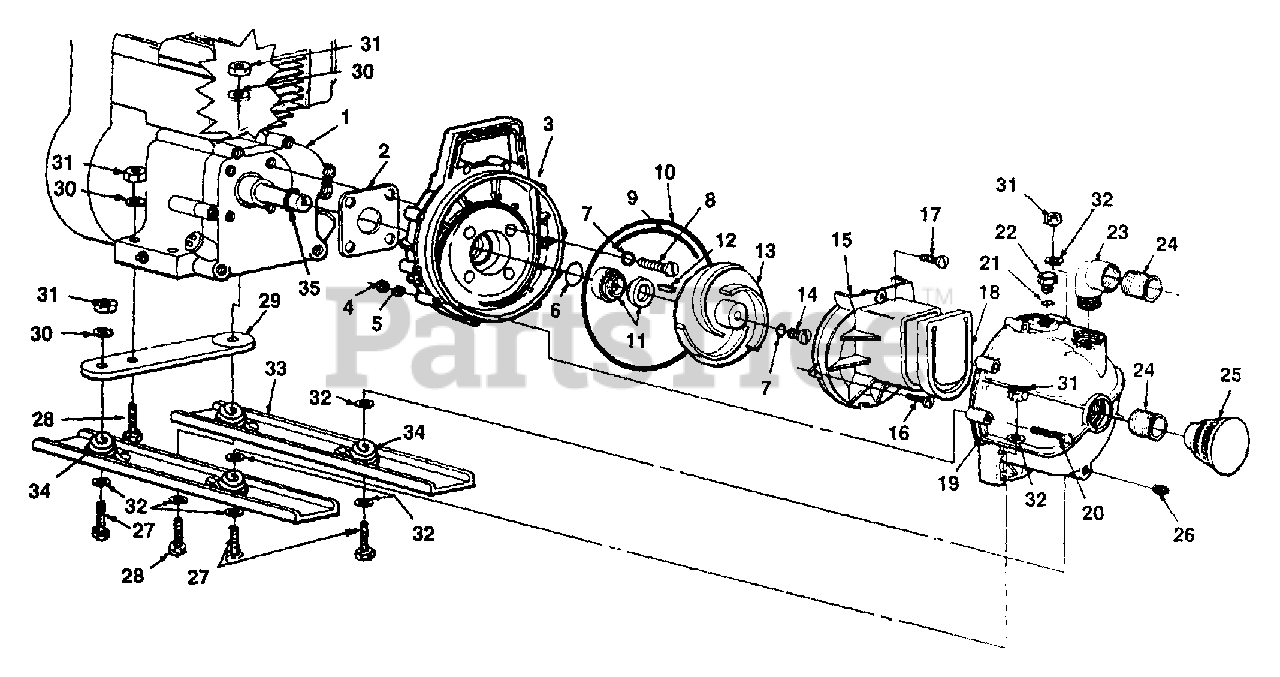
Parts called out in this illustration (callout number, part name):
1	ENGINE
2	SHIM
3	HOUSING - Impeller
4	NUT - Hex 1/4 - 20
5	WASHER - Lock 1/4
6	"O" RING
7	"O" RING, Screw
8	SCREW, Bracket, Impeller Hsg.
9	"O" RING, Segment
10	"O" RING, Body
11	SHAFT SEAL
12	KEY, 3/16 x 3/16 x 1
13	IMPELLER
14	SCREW, Impeller, rd. hd. 5/16-24 x 3/4
15	VOLUTE
16	SCREW - Volute 6-32 x 1/2 rd. hd.
17	SCREW - Volute top (10-24 x 1 1/2) rd. hd.
18	CHECK VALVE
19	BODY 2"
20	SCREWS - Body fil. (1/4-20 x 2 1/2)
21	"O" RING - Fil. plug
22	PLUG - Filler
23	ELBOW - Street, 2"
24	NIPPLE - 2"
25	STRAINER, 2"
26	PLUG - Drain
27	SCREW - Hex 5/16-18 x 7/8"
28	SCREW - 5/16-18 x 1 1/2"
29	BAR - Mounting
30	WASHER - Lock 5/16 heavy
31	NUT - Hex hd., 5/16-18
32	WASHER - Flat, 5/16
33	SKID
34	SPRING - Foot
35	SLINGER
